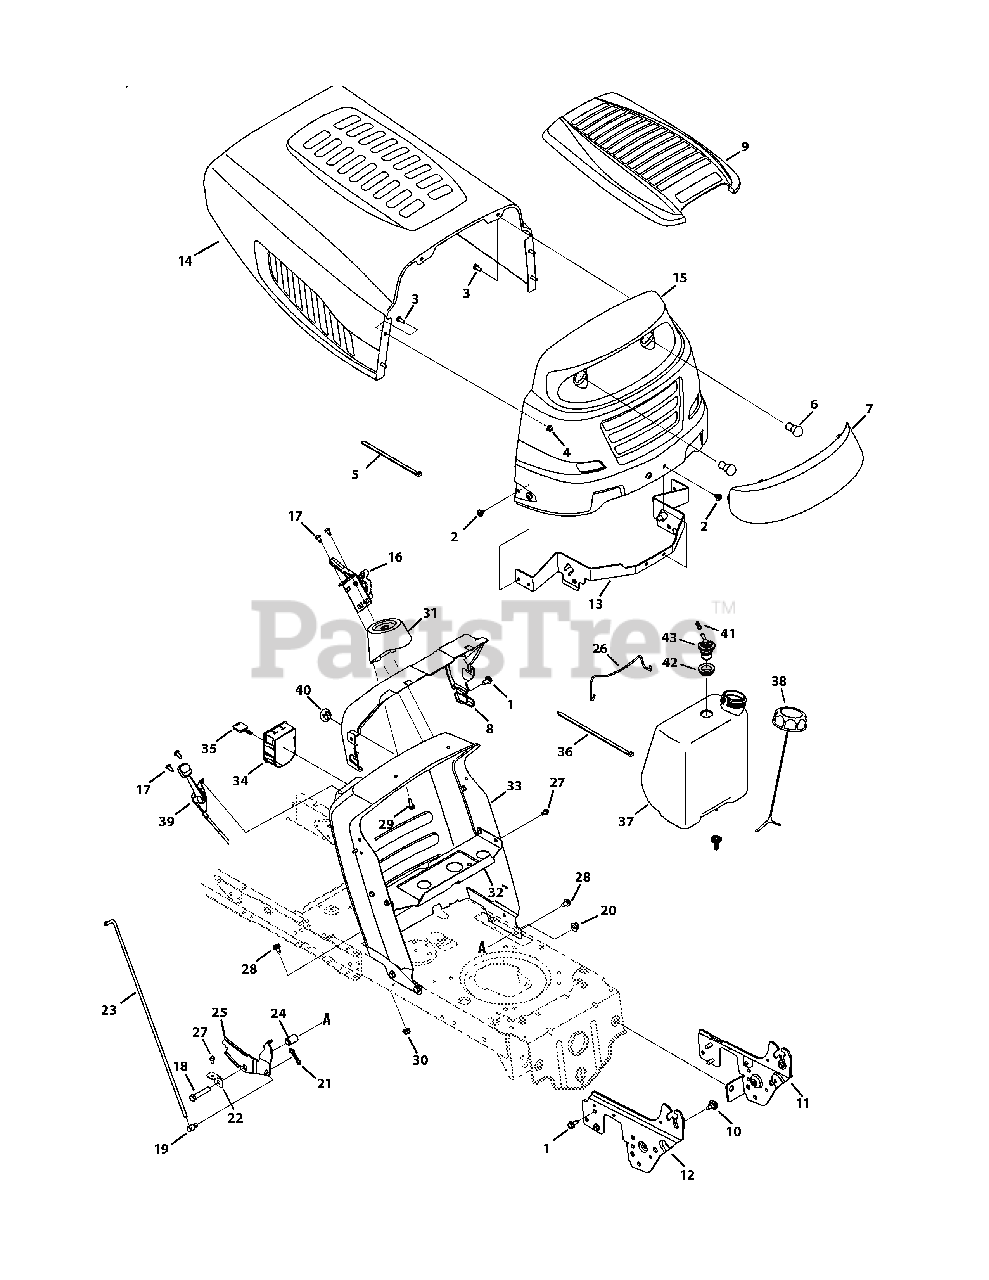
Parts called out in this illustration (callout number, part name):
1	Screw 5/16-18 x .750
2	Screw 5/16-18 x .375
3	Hex Screw 1/4-20 x .620
4	Flanglock Nut 1/4-20
5	Cable Tie
6	Miniature lamp 12V socket
7	Grill Lens
8	Dash Collar
9	Hood cover
10	Shoulder Screw .43 x .29
11	Suppport Bracket LH
12	Suppport Bracket RH
13	Hood pivot bracket
14	Hood - 5 Style
15	Grill
16	Hydro Control Assembly
17	Screw 1/4-20 x .500
18	Hex Screw 3/8-16 x 2.00
19	Ferrule Adjust
20	Flang lock Nut 3/8-16
21	Cotter Pin, Bow Tie
22	Speed Latch Tab
23	Control Rod, Speed Selector
24	Flang Spacer .390 x .671 x 1.095
25	Transmission Speed Latch, RMC
26	Battery Rod
27	Hex Screw Washer 1/4-20 x .500
28	Screw 5/16-18 x .625
29	Hex Screw 1/4-15 x .750
30	Flanglock Nut 5/16-18
31	Support Shaft
32	Gas Tank Support Bracket
34	Key Switch Module, 8 Pin
34	Key Switch 3 Position, 5Pin
36	Cable Tie
37	1.36 Gallon Fuel Tank EPA
38	Fuel Cap, 2.25" EPA
39	Throttle/Choke Control Cable
40	Choke Plug
41	Hose Vent, 3/16 EPA
42	Rubber Grommet, 23 x 3.55
43	Rollover Valve
